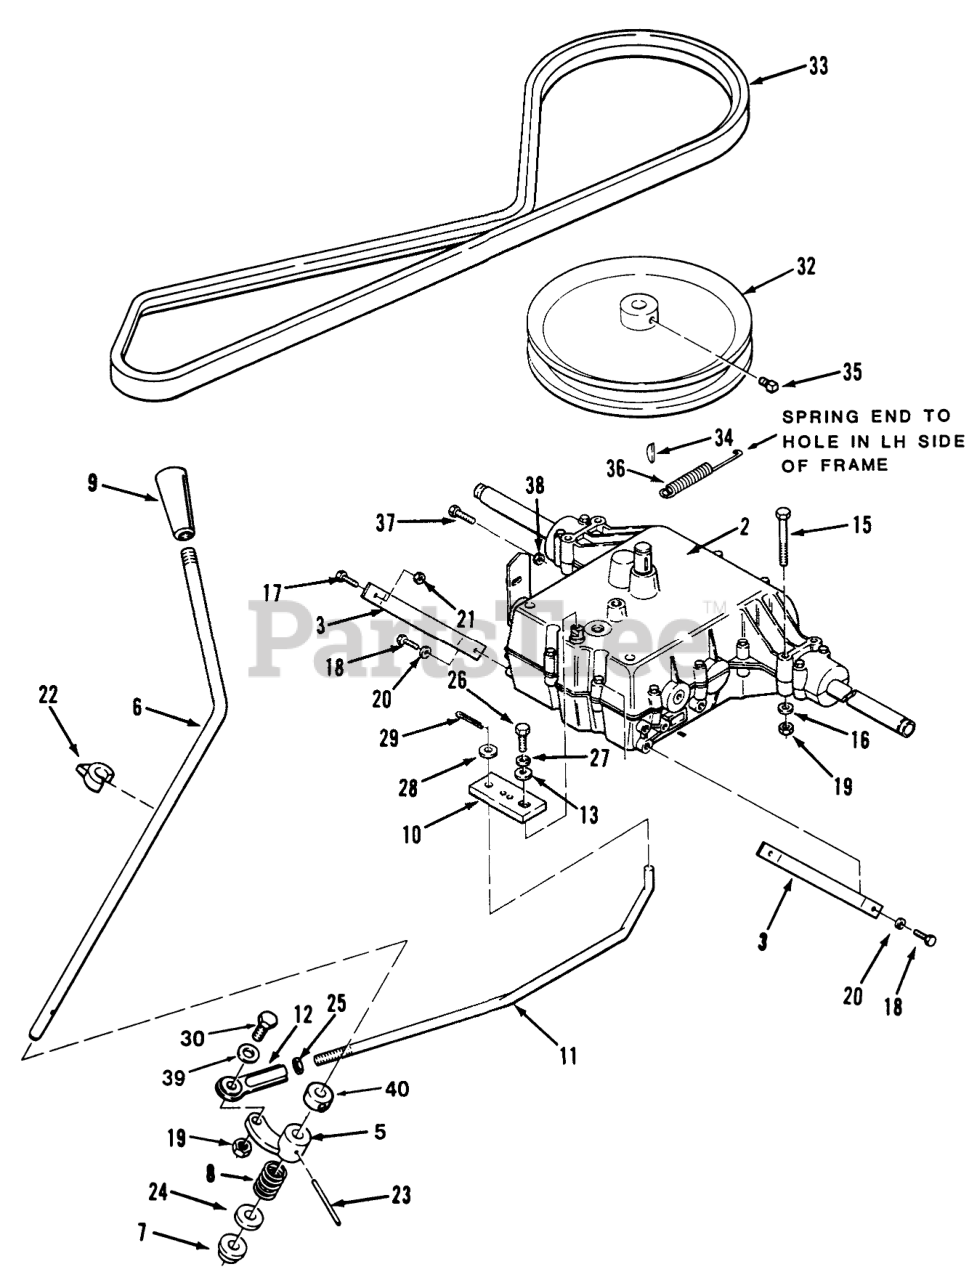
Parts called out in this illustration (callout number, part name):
2	ASS'Y TRANSAXLE 5-SP
3	TORQUE-STRAP R
5	ARM SHIFTER B
6	ROD-SHIFT LEVER
7	BUSHING-NYLINER
8	SPRING COMPRESSION
10	ARM-TRANSMISSION 5SP
11	ROD-LINKAGE
12	END-ROD
13	WASHER
15	HHCS
16	WASHER-PLAIN
17	CARRIAGE BOLT -4
18	Screw
19	NUT-LOCK, NI
20	Lockwasher
21	Nut
22	POINTER
23	SPIROL PIN 7/32X21/2
24	SHIM-WASHER
25	Nut
26	Bolt 1/4-28 X 7/8
27	Washer
28	WASHER 5/16 SAE
30	Bolt
32	PULLEY-TRANS
33	BELT-V
34	KEY-HI-PRO
35	Set Screw
36	SPRING-EXTENSION
37	Bolt
38	Nut
39	WASHER-PLAIN
40	COLLAR
